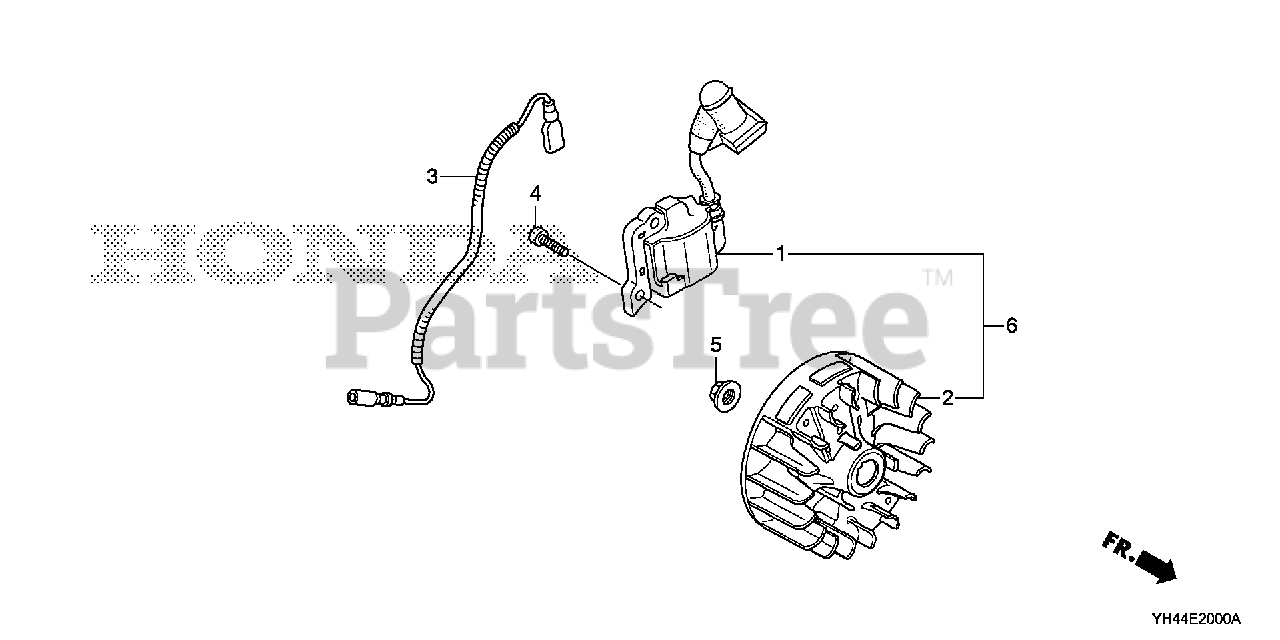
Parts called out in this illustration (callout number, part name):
1	COIL ASSY., IGNITION
2	FLYWHEEL
3	WIRE, STOP SWITCH
4	BOLT, SOCKET (4X14)
5	NUT, FLANGE (7MM)
6	IGNITION COIL & FLYWHEEL KIT
